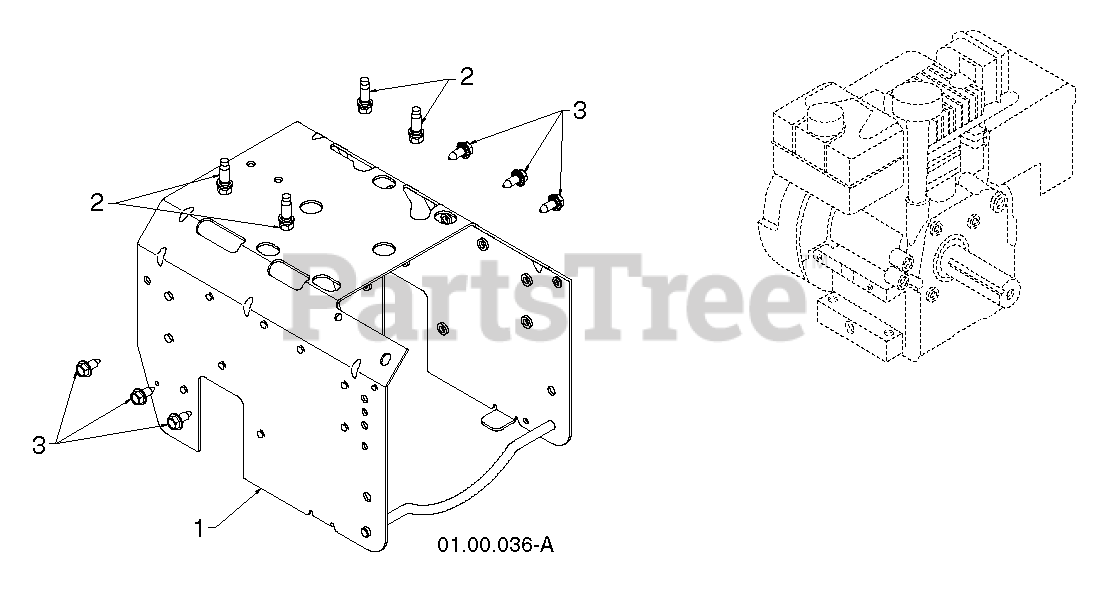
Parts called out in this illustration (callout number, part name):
1	FRAME.WELD.HYDRO.668.PNT
2	BOLT 3/8-16X1-1/8
3	BOLT.HEX.HD.WASHER.5/16-18X.75
